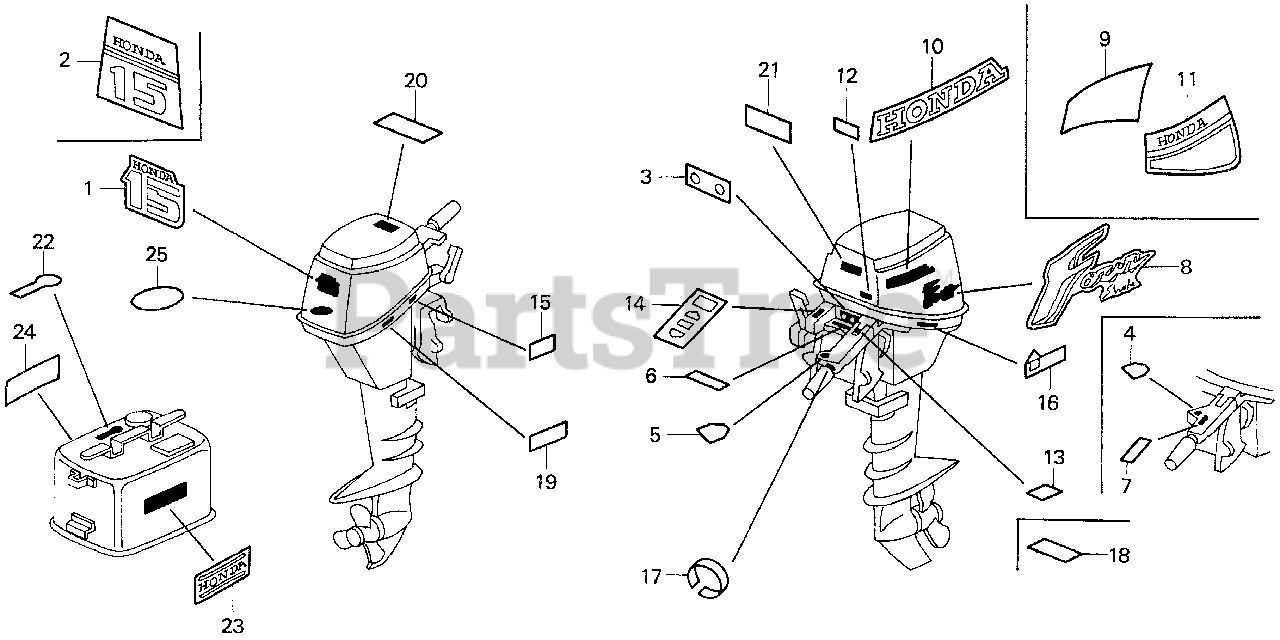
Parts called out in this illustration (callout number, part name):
1	MARK, RR. (9.9)
3	LABEL, INDICATION (E)
4	MARK, EMERGENCY SWITCH INDICATION (ENGLISH)
6	MARK, STARTER (ENGLISH)
7	MARK, SPARE CLIP (ENGLISH)
8	MARK, SIDE
10	MARK, SIDE STRIPE (HONDA)
10	MARK, SIDE STRIPE
13	LABEL, SPECIFICATION
14	MARK, CHANGE (ENGLISH)
15	MARK, RECEPTACLE (6A)
16	LABEL, OIL CAUTION (E)
17	MARK, THROTTLE (E)
19	LABEL, STORING CAUTION (ENGLISH)
20	LABEL, OPERATOR CAUTION (ENGLISH)
